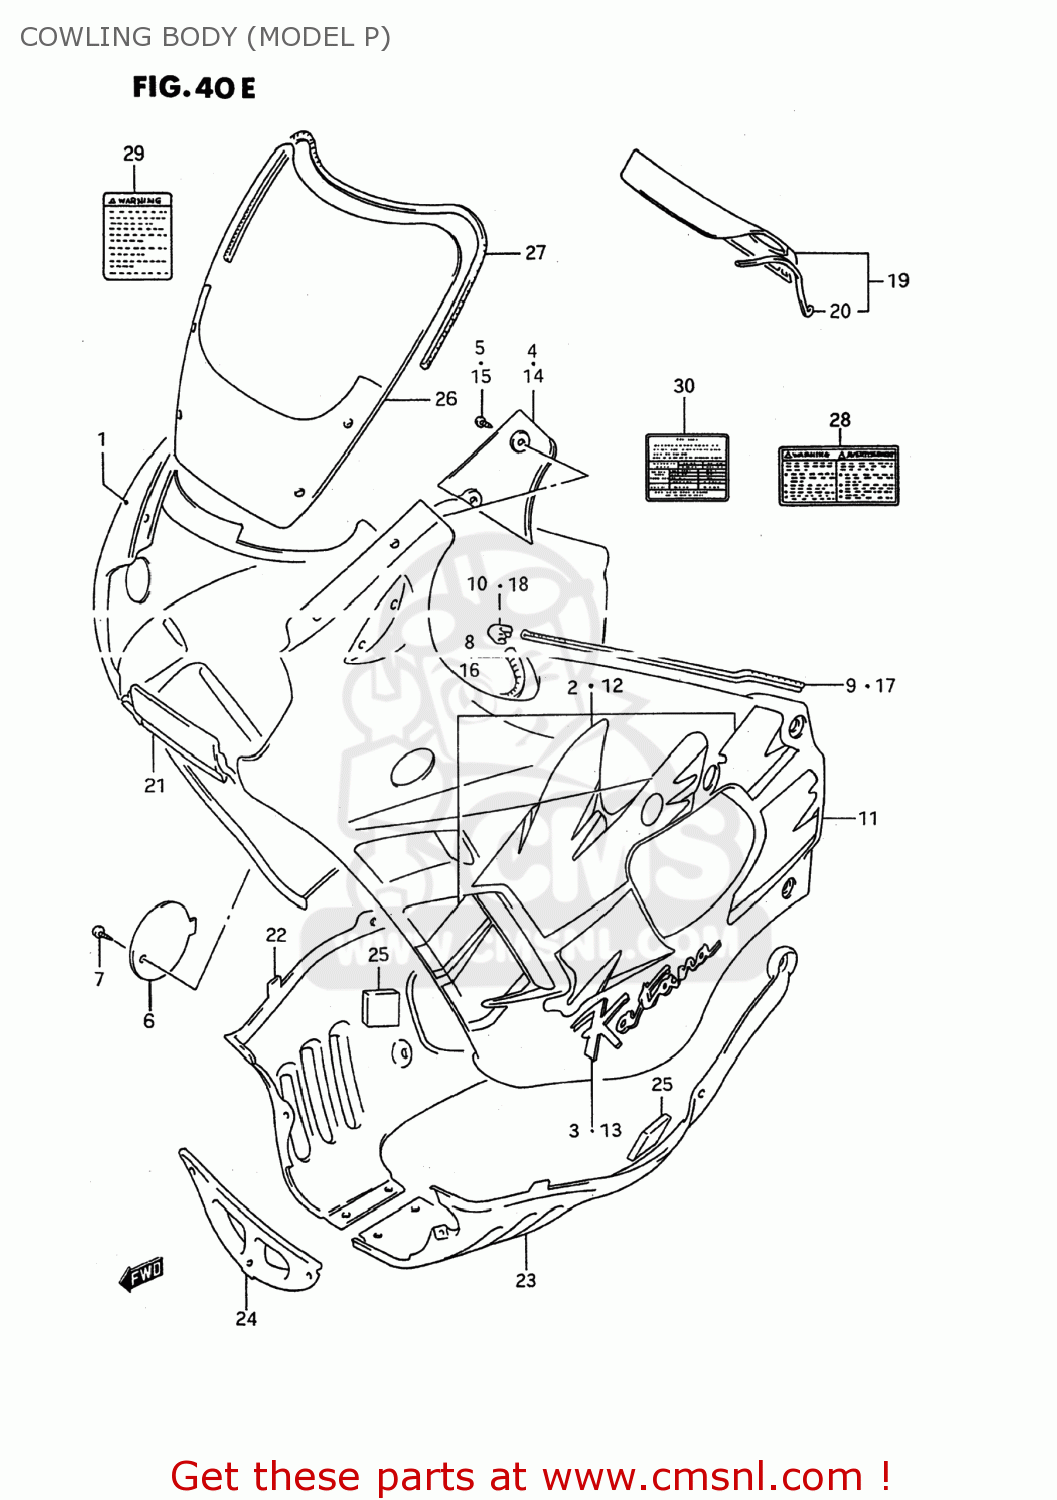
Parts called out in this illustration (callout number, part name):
1	COVER ASSEMBLY,COWLING,RIGHT
2	TAPE SET,COWLING SIDE,R
3	EMBLEM,BODY COWL SIDE
4	COVER,COWLING METER,SIDE
5	SCREW
6	LID,OIL
7	SCREW(6X16)
8	MOLD,COWLING
9	MOLDING
10	JOINT,MOLDING END
11	COVER ASSEMBLY,COWLING,LEFT
12	TAPE SET,COWLING SIDE
13	EMBLEM,BODY COWL SIDE
14	COVER,COWLING METER SIDE,L
15	SCREW
16	MOLD,COWLING
17	MOLDING
18	JOINT,MOLDING END
19	COVER,METER
20	MOLDING
21	PANEL,COWLING CTR
22	COVER,COWLING UNDER,R
23	COVER,COWLING UNDER,L
24	COVER,COWLING UNDER FR
25	CUSHION,UNDER COWLING
26	WINDOW,COWLING
27	MOLDING
28	LABEL,GENERAL WARNING
29	LABEL (WARNING SCREEN)
30	LABEL (TIRE INFORMATION)
